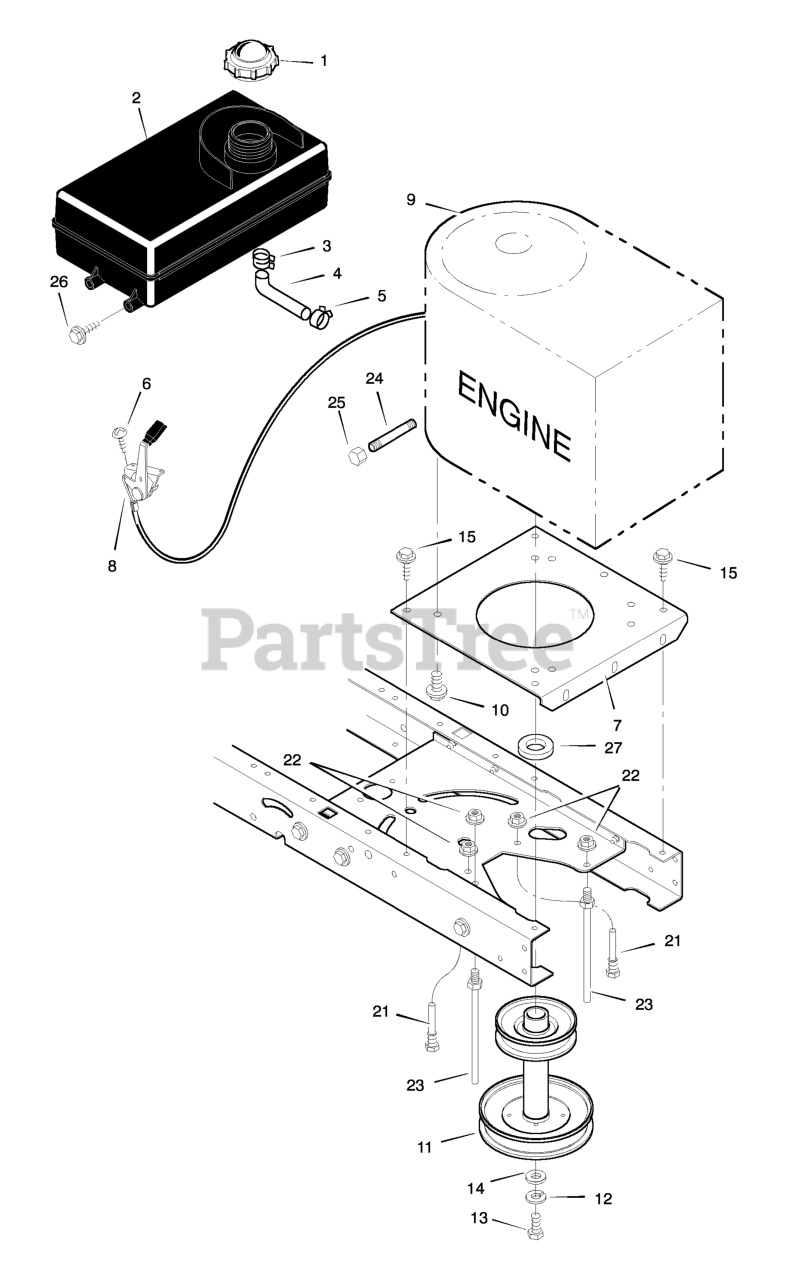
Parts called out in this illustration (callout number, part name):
1	Fuel Cap
2	TANK, Fuel 1.4 Gal.
3	Hose Clamp
4	Fuel Line
5	Hose Clamp
7	Plate, Engine
8	Throttle Control
9	Engine *
10	Bolt, Engine Mount
11	Stack Pulley Assembly
12	Lockwasher
13	Bolt, Hex
21	Guide, Belt
22	Nut, Flange
23	Guide, Belt
24	Pipe, Oil Drain
25	Cap, Oil Drain
